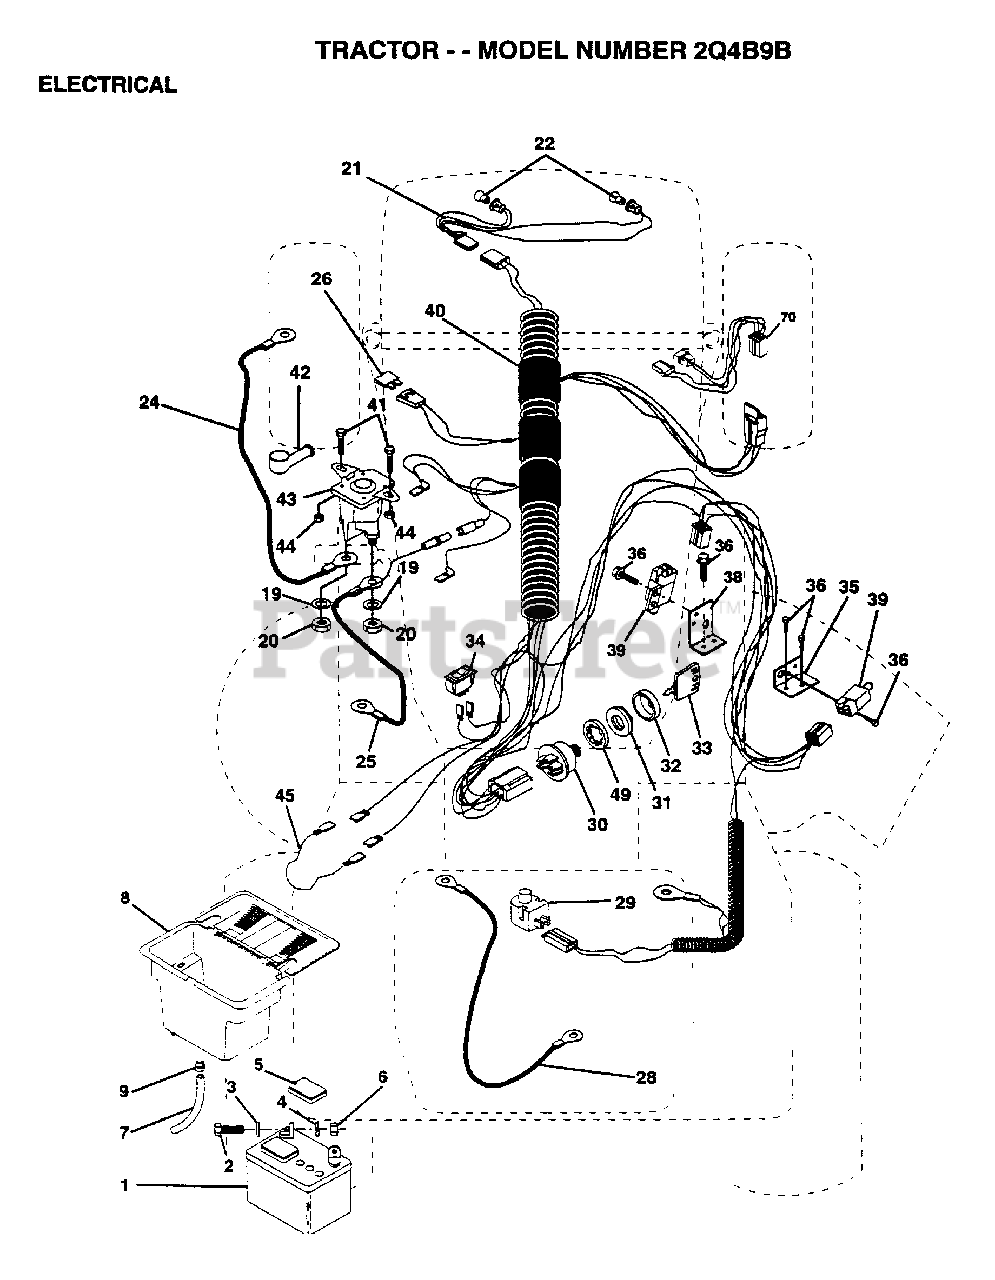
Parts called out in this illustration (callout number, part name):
2	BOLT LT
3	WASHER
4	LOCKWASHER
5	"CAP,BATTERY "
7	TUBE T
9	HOSE CLAMP T
20	NUT
21	"HARNESS,LIGHT SOC"
22	HEADLAMP BULB
24	"CABLE T, BATTERY"
25	CABLE.BTRY.6GA.RD
26	FUSE HYT
28	CABLE T
29	SWITCH SEAT
32	COVER KEY SWITCH
33	KEY MLD GEN DELTA
34	SWITCH LT
35	BRACKET LT
36	SCREW
38	BRACKET SWITCH IN
39	SWITCH INTERLOCKT
40	HARNESS.IGN.DASH.
41	BOLT.HX.1/4-20
44	NUT
45	ADAPTER AMMETER
49	LOCKWASHER
70	HARNESS.ENG.DUAL
